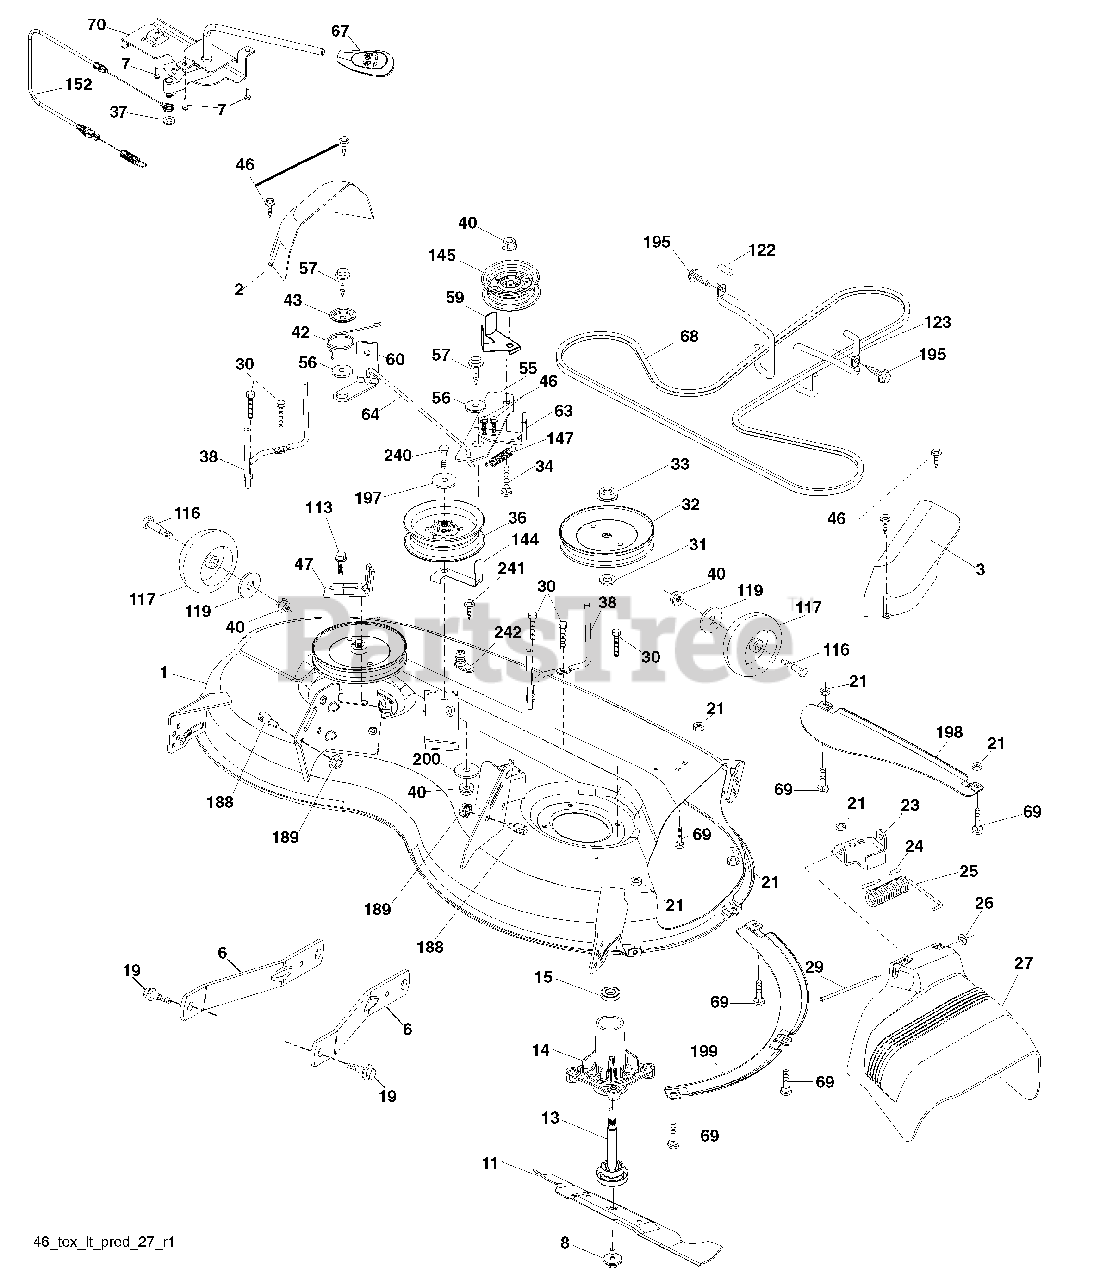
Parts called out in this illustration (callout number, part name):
1	Mower Housing
2	Cover Mandrel Rh
3	Cover Mandrel Lh
6	Arm Suspension
7	Screw #10 X 0.750 Bos Thread
8	Bolt/Washer Asm 7/16-20 Unf
11	Blade Mower
13	Shaft Assembly, Mandrel
14	Housing, Mandrel
15	Bearing, Ball, Mandrel
19	Bolt, Shoulder
21	Nut
23	Bracket, Deflector
24	Cap, Sleeve
25	Spring, Torsion, Deflector
27	Shield, Deflector
29	Rod, Hinge
30	Screw Thdrol Rolling Wsh Hd
31	Washer, Spacer
32	Pulley, Mandrel
33	Nut, Toplock, Flanged
34	Bolt Carr Sh. 3/8-16 X 1-1/2 Gr. 5
36	Pulley, Idler, 4.50 Raw
37	Washer 13/32 X 13/16 X 16 Ga.
38	Keeper Belt Mandrel
40	Nut, Lock Flg. 3/8-16 Unc
42	Spring Trosion Brake
43	Spring Torsion Retainer
47	Bracket Clutch Cable
55	Arm, Idler
56	Spacer, Retainer
57	Screw Hexwsh Thd 3/8-16 X 1
59	Guard, Tuv Idler (94)
60	Arm Brake Mower Lh
63	Arm Brake Mower
64	Linkage Brake
67	Handle, Clutch Cable
68	V-Belt
69	Bolt
70	Clutch Asm. Cable
113	Screw 5/16-18
116	Bolt, Shoulder
117	Wheel, Gauge
119	Washer 13/32 X 1-1/4 X 12 Ga.
122	Keeper Belt Eng. Lh
123	Keeper Belt Eng. Rh
144	Keeper Belt
145	Pulley Idler
147	Spring Return
152	Cable Clutch Manual W/Spr.
188	Stud Fastener
189	Nut Lock Hex Flange
195	Screw 3/8-16 X 3/4
197	Washer 13/32 X 13/16 X 12 Ga.
198	Baffle Center Front
199	Baffle Front Rh
200	Washer 13/32 X 1 X 1/2 Ga.
240	Bolt 3/8-16 Unc X 2-1/4 Gr. 5
241	Screw Tt #10-32.5 3/8 Flg.
242	Port Washout
